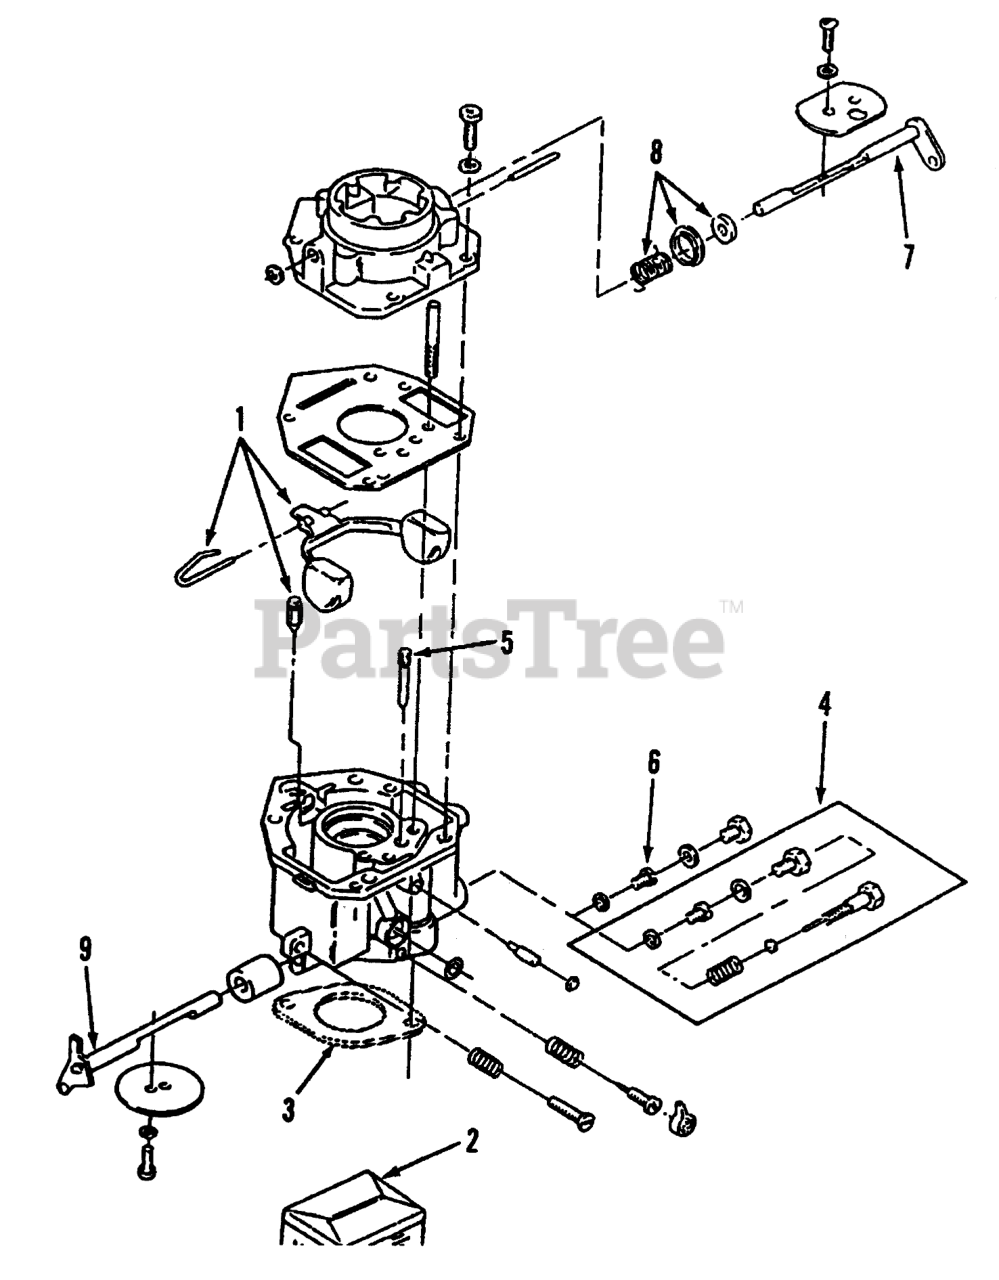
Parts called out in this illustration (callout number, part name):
1	Kit-Float (Includes Float, Pin, & Valve)
2	Kit-Repair (Includes) Screw & Plug Package, Gasket Package, Float Valve, Idle Adjust Needle & Spring, Mounting Gaskets, & Idle Limit Cap)
3	Oil Fill Tube
4	FIXED-JET
5	IDLE-JET
6	POWER JET
7	Kit-Shaft, Choke (Includes Choke Valve, Valve Setscrew, & Air Filter)
8	Kit-Lever, Choke (Includes Choke Lever Ring, Choke Spring, & Choke Collar)
9	Kit-Shaft, Throttle (Includes Valve Setscrew, Air Filter, & ThroWe Valve)
